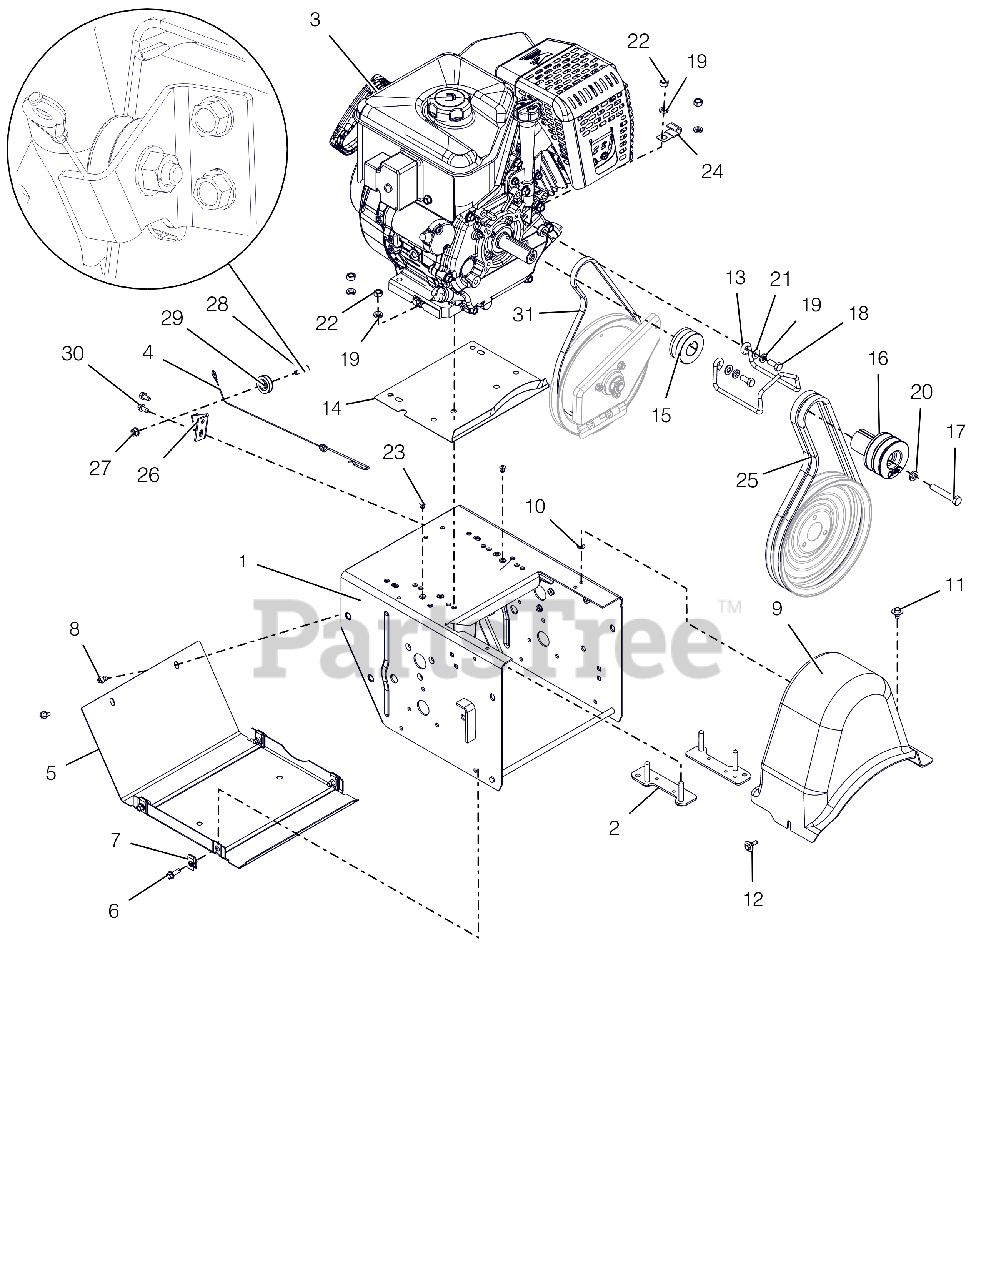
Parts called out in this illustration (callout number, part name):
1	FRAME, MAIN-DELUXE(WELDMENT)
2	STRAP, ENGINE-MEDIUM BLOCK
3	ENGINE,EFI306 GEN3 120V/60W
4	CABLE, LOWER TRACTION,SS & PRO
5	COVER, BOTTOM
6	BLT-HEX .25-20X.75 HWH YZ GR5
7	NUT-RTNR .25-20X.56
8	SCR-TAP .25-20X.50 HWH TR YWZ
9	COVER, BELT-LARGE
10	NUT-PUSH .25X.50 O.D.
11	SCR-TAP .25-20X.50 LGHWH TR YZ
12	SCR-TAP .25-20X.5 CAPTIVE
13	FINGER, BELT
14	BAFFLE, WATER - LARGE BLOCK
15	SHEAVE, DRIVE
16	SHEAVE,ATTACHMENT-SHO 2 GRV
17	BLT-HEX .38-24X2.25 YWZC GR5
18	BLT-HEX .31-24X.75 YWZC GR5
19	WSHR-LK .312X.097 HVY YWZC
20	@WSHR-LK .38X.094 REG YWZC
21	@WSHR-FL-STL.344X.688X.065YWZC
22	@NUT-HEX .31-18 YWZC
23	RVT-POP .187 YZ
24	J-CLAMP
25	V-BELT, HA-RAW EDGE (SET)
26	BRACKET, CABLE PULLEY
27	@NUT-LK-TOP-FLG .25-20 YWZC
28	BOLT, SHLDR-.375X.375X.25-20
29	PULLEY, CABLE
30	SCR-TAP .25-20X.50 HWH TR YWZ
31	V-BELT, 3L-WRAPPED
